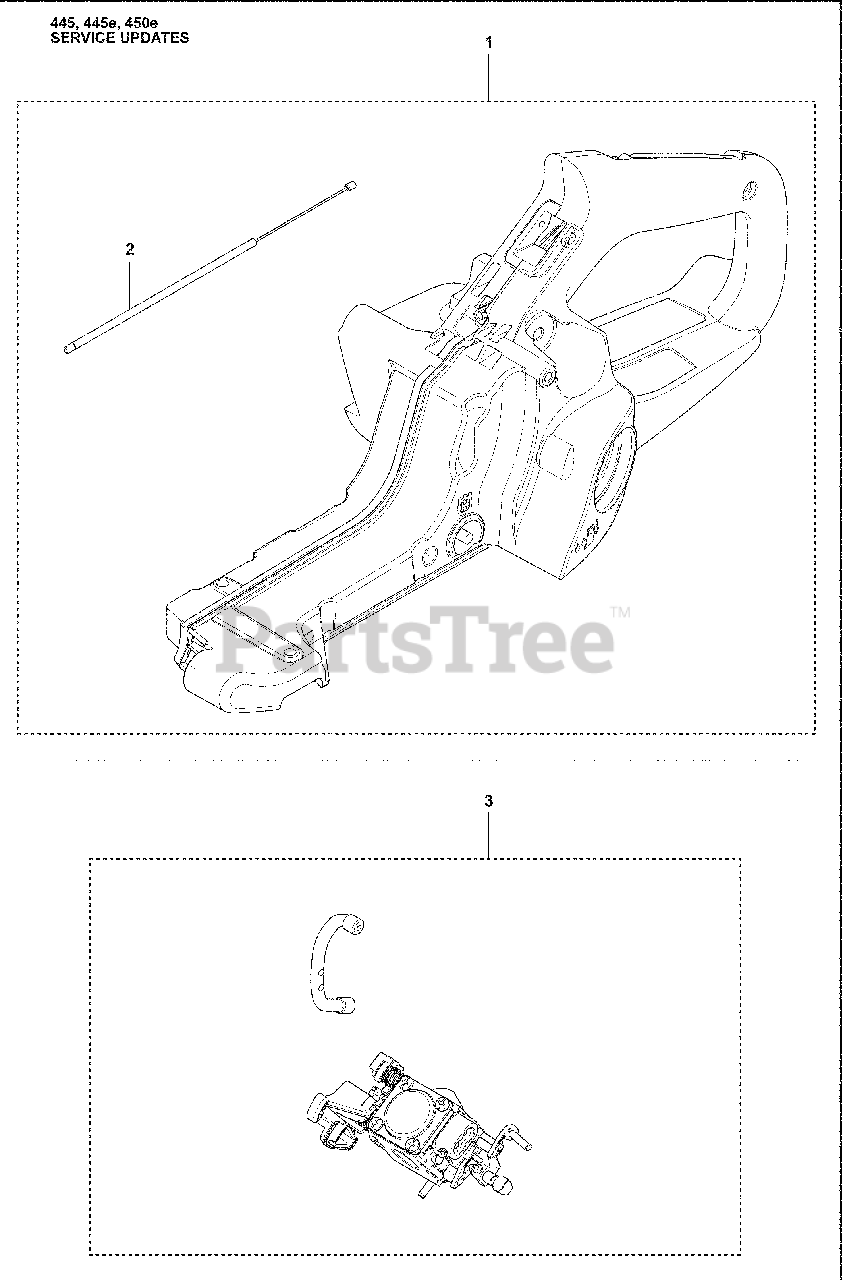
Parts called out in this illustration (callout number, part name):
1	Up to 08220001
2	Up to 08220001
3	Up to 08220001
